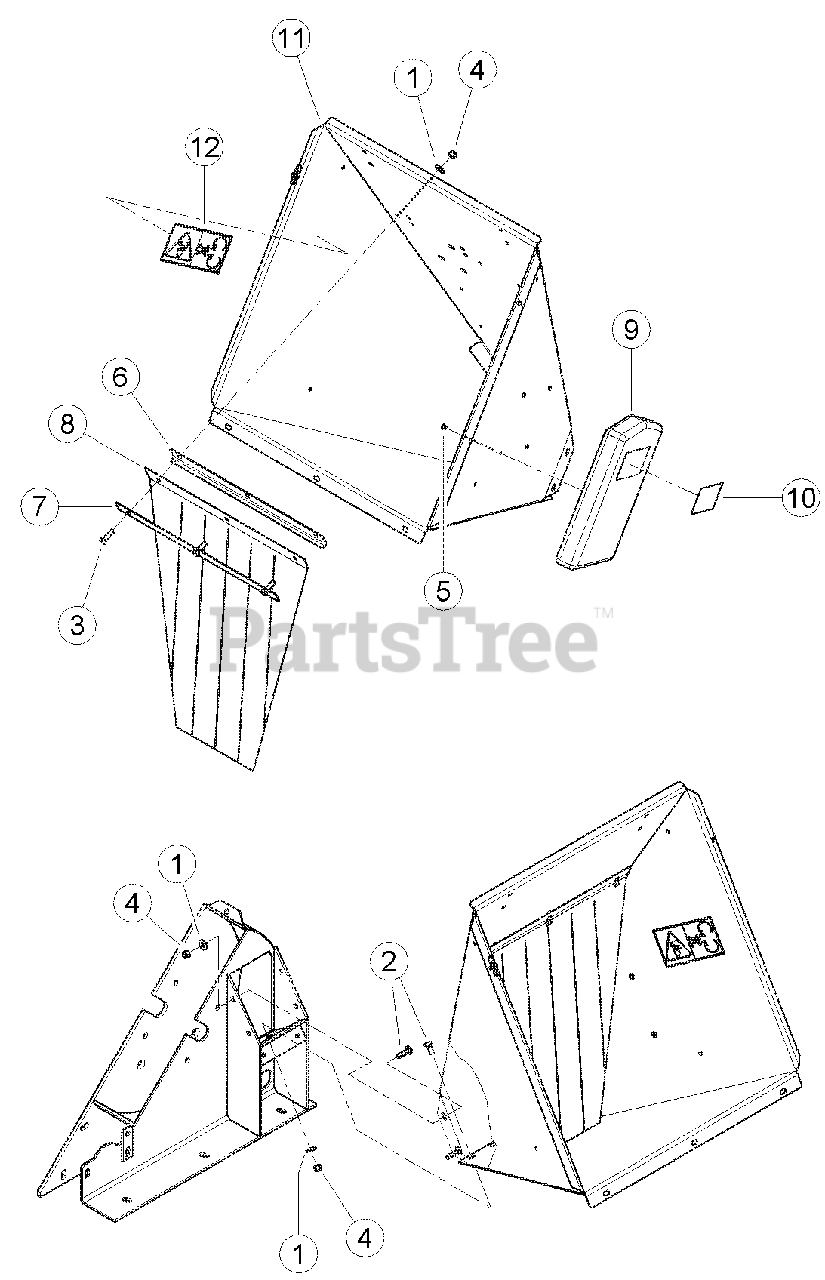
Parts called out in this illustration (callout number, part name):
1	WASHER, 3/8 FLAT ZP
2	BOLT, 3/8 X 1 CRG GR5 NC ZP
3	BOLT, 3/8 X 1-1/4 HEX HD GR5 ZP
4	NUT, 3/8 NE NYLOCK ZP
5	RIVET, 1/4 X 1/2 DOME HD BLIND SS
6	ANGLE, FLAP ANCHOR
7	STRIP, FLAP RETAINER
8	FLAP, CHIPPER CHUTE
9	ASSEMBLY, MANUAL CONTAINER SERVICE PART
10	DECAL, MUTILINGUAL MANUAL
11	ASSEMBLY, 5 INCH CHIPPER CHUTE SERVICE PART
12	DECAL, BLADE DANGER ISO
